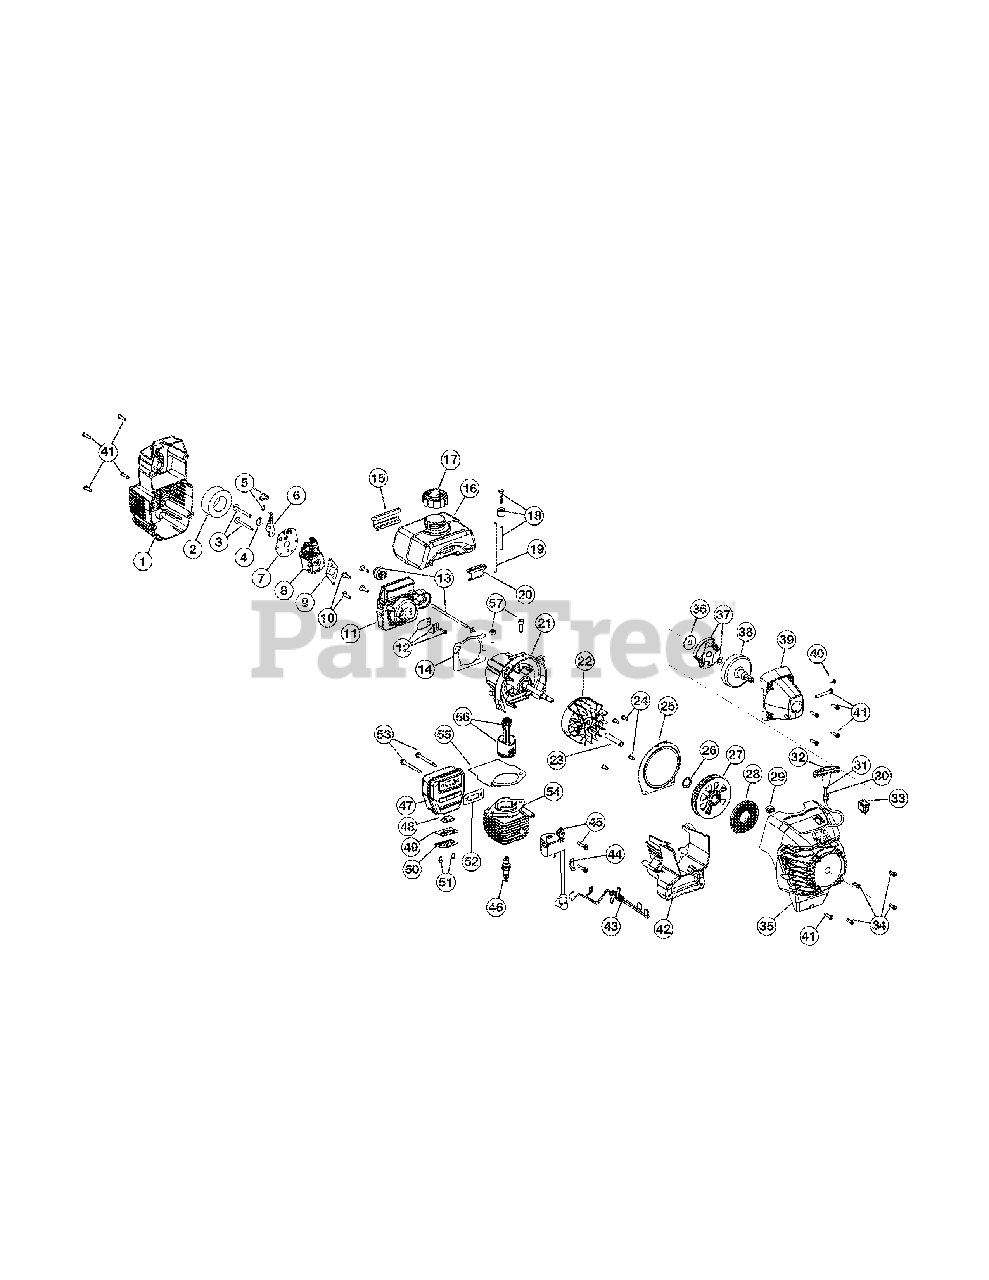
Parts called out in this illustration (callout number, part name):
1	Air Cleaner Cover Assembly (includes 2 & 41)
2	Air Cleaner Filter
3	Carburetor Mounting Screw Assembly
4	Wavey Washer
5	Choke Knob
6	Choke Lever (includes 5)
7	Choke Plate (includes 6)
8	Carburetor Assembly (includes 9 & 18)
9	Carburetor Gasket
10	Carb Mount Screw
11	Carb Mount Assembly (includes 10, 12 & 14)
12	Reed Assembly
13	Primer and Hose Assembly
14	Carburetor Mount Gasket
15	Rear Mounting Pad
16	Fuel Tank Assembly (includes 17 & 19)
17	Fuel Cap
18	Fuel Line Assembly
19	Fuel Return Line
20	Front Mounting Pad
21	Crank Case Service Assembly (includes 10)
22	Flywheel Assembly
24	Pressure Plate Screw
25	Pressure Plate (includes 24 & 29)
26	Pulley Retainer
27	Recoil Pulley Assembly (includes 26)
28	Recoil Spring
29	Rope Guide Retainer
30	Rope Guide
32	Pull Handle
34	Housing Screw
35	Starter Housing Assembly (includes 24-34 & 41)
36	Clutch Washer
37	Clutch Rotor Assembly
38	Clutch Drum Assembly
39	Clutch Cover Assembly (includes 40 & 41)
40	Anti-Rotation Screw
41	Cover Screw
42	Shroud Extension & Stand (includes 41)
43	Wire Leads and Sleeve
44	Ground Tab
45	Module Assembly
46	Spark Plug
47	Muffler Assembly (includes 48 & 49)
48	Exhaust Gasket
49	Muffler Mounting Bolts
50	Cylinder Assembly (includes 52 & 53)
51	Piston and Rod Assembly
52	Cylinder Gasket
53	Cylinder Bolt
